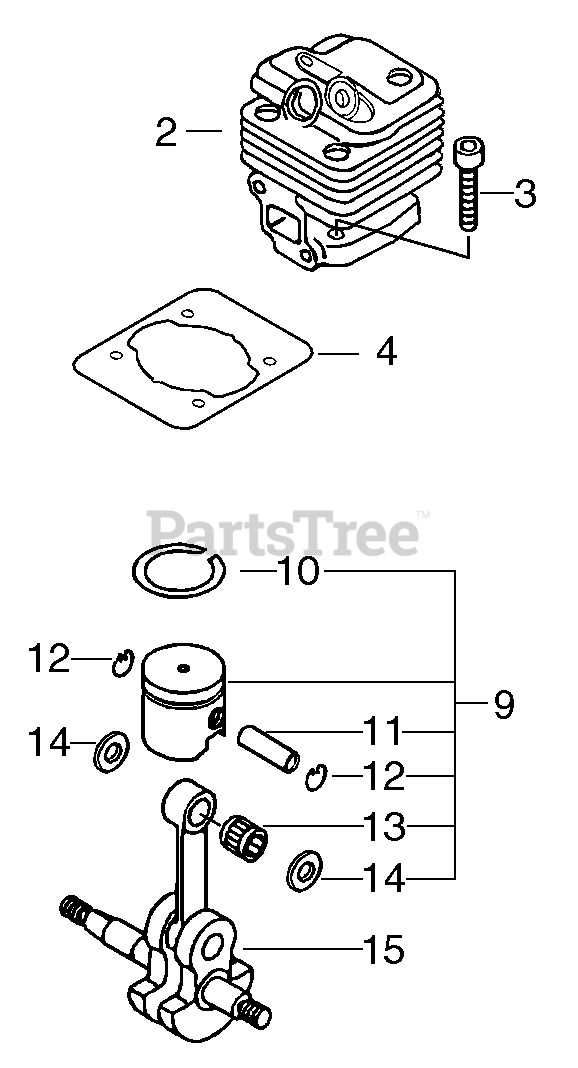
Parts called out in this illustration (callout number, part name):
2	CYLINDER
3	SCREW - 5X20
4	GASKET, CYLINDER
9	PISTON KIT
10	RING, PISTON
11	PIN, PISTON
12	RING, RETAINING - 8
13	BEARING, NEEDLE - 10
14	WASHER - 10
15	CRANKSHAFT ASSY
